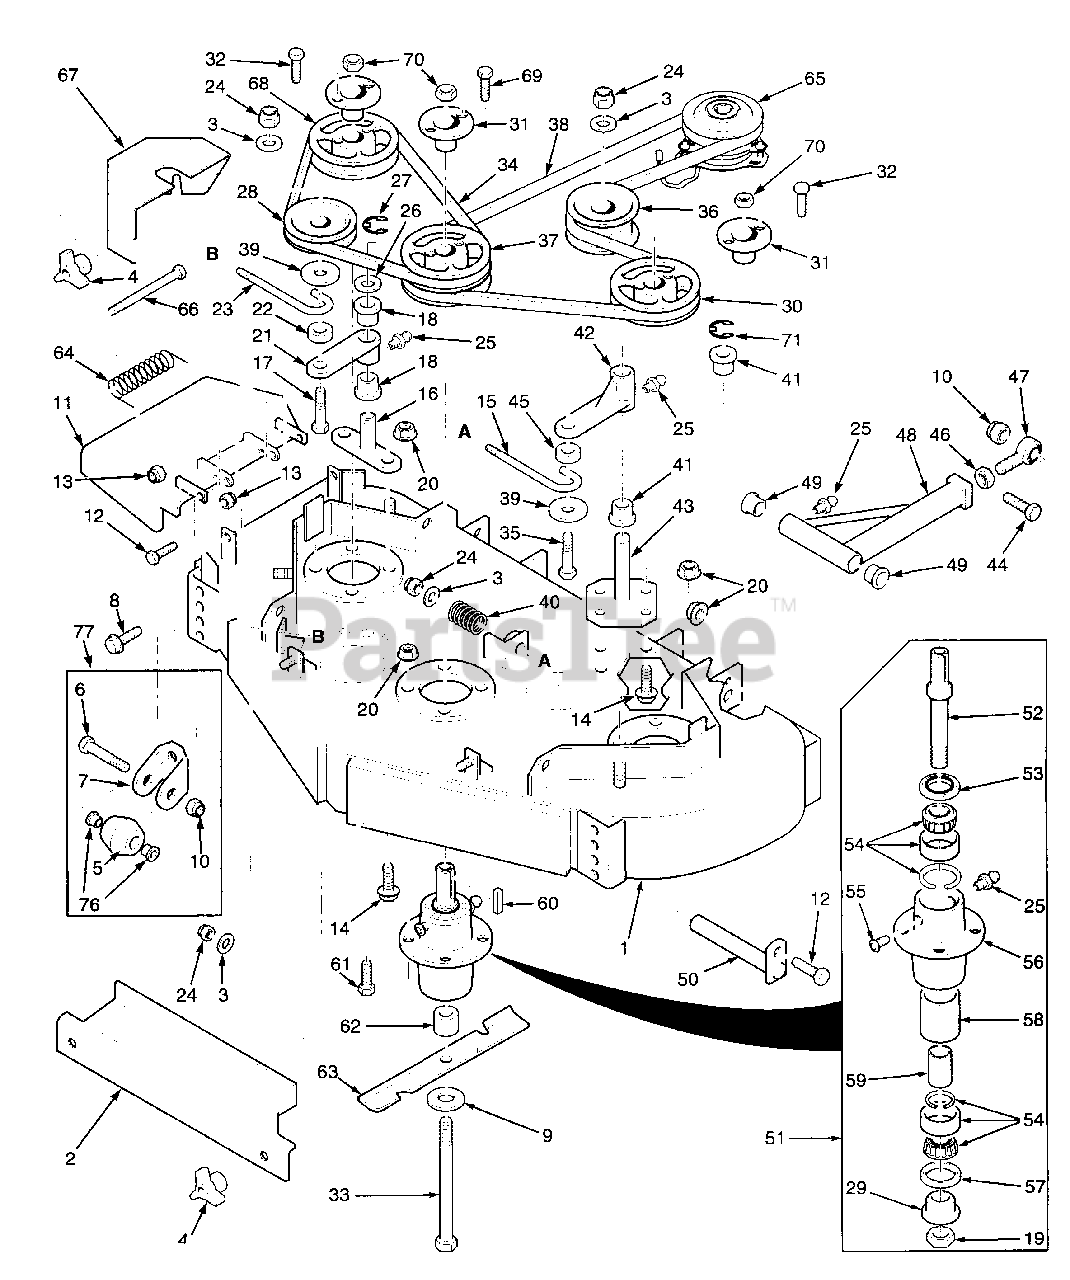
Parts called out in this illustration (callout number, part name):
1	Cutter Deck
2	Belt Cover, Front
3	Flatwasher, 3/8" Special (.391 x .938 x .105)
4	Wing Nut, 3/8-16
5	Anti-Scalp Wheel
6	Bolt, carriage 3/8-16 x 4"
7	Anti-Scalp Wheel Bracket
8	Bolt, Hex Serrated Flange 3/8-16 x 1"
9	Flatwasher, 5/8" (.688 x 1.75 x .134)
10	Nut, Lock 3/8-16 Center Lock
11	Discharge Chute
12	Bolt, Hex Head 5/16-18 x 1"
13	Nut, Hex Elastic Stop 5/16-18
14	Bolt, Hex Serrated Flange 5/16-18x 3/4"
15	"J" Rod
16	Idler Pivot Base
17	Bolt, Hex Head 3/8-16 x 2-1/4"
18	Bushing
19	Nut, Special 1-1/16-18
20	Nut, Hex Serrated Flange 5/16-18
21	Idler Arm
22	Spacer
23	"J" Rod
24	Nut, Hex Elastic Stop 3/8-16
25	Grease Fitting
26	Flatwasher, 3/4"
27	Ring, Retaining 3/4" External "E"
28	Pulley, Idler
29	Spindle Bushing, Bottom
30	Pulley, LH Spindle
31	Tapered Hub, 1-1/8 Bore
32	Bolt, Hex Head 1/4-20 x 3/4"
33	Bolt, Hex Head 5/8-11 x 9-1/2"
34	Belt, RH Blade Drive
35	Bolt, Hex Head 3/8-16 x 4-1/2"
36	Pulley, idler Cutter Engagement
37	Pulley, Double Groove
38	Belt, Blade Drive
39	Flatwasher, 3/8" (.375 x 1.5 x .06)
40	Spring, Idler Tension
41	Bushing
42	Idler Arm
43	Idler Pivot Base
44	Bolt, Hex Head 5/8-11 x 3"
45	Spacer
46	Nut, Hex 5/8-18 UNF
47	Rod End
48	Push Arm
49	Bushing
50	Push Arm Shaft
51	Spindle Assembly
52	Spindle Shaft
53	Seal, Top
54	Bearing Assembly
55	Relief Fitting, Tapered Spindle
56	Spindle Housing
57	Seal, Bottom
58	Spacer, Outside
59	Spacer, Inside
60	Key, 1/4 x 1/4 x 2"
61	Bolt, Hex Head 5/16-18 x 1-1/4"
62	Spacer, Tapered Spindle
63	Cutter Blade, 18" Standard
64	Spring, Discharge Chute
65	Electric Clutch
66	Bolt, Hex Head 5/16-18 x 4.25"
67	Belt Cover, LH
68	Pulley, RH Spindle
69	Bolt, Hex Head 1/4-20 x 1.375 Full Thread
70	Nut, Hex 5/8-11 UNC
71	Ring, Retaining 1-1/8" External "E"
76	Bushing, Anti-Scalp Wheel
77	Anti-Scalp Wheel Assembly
